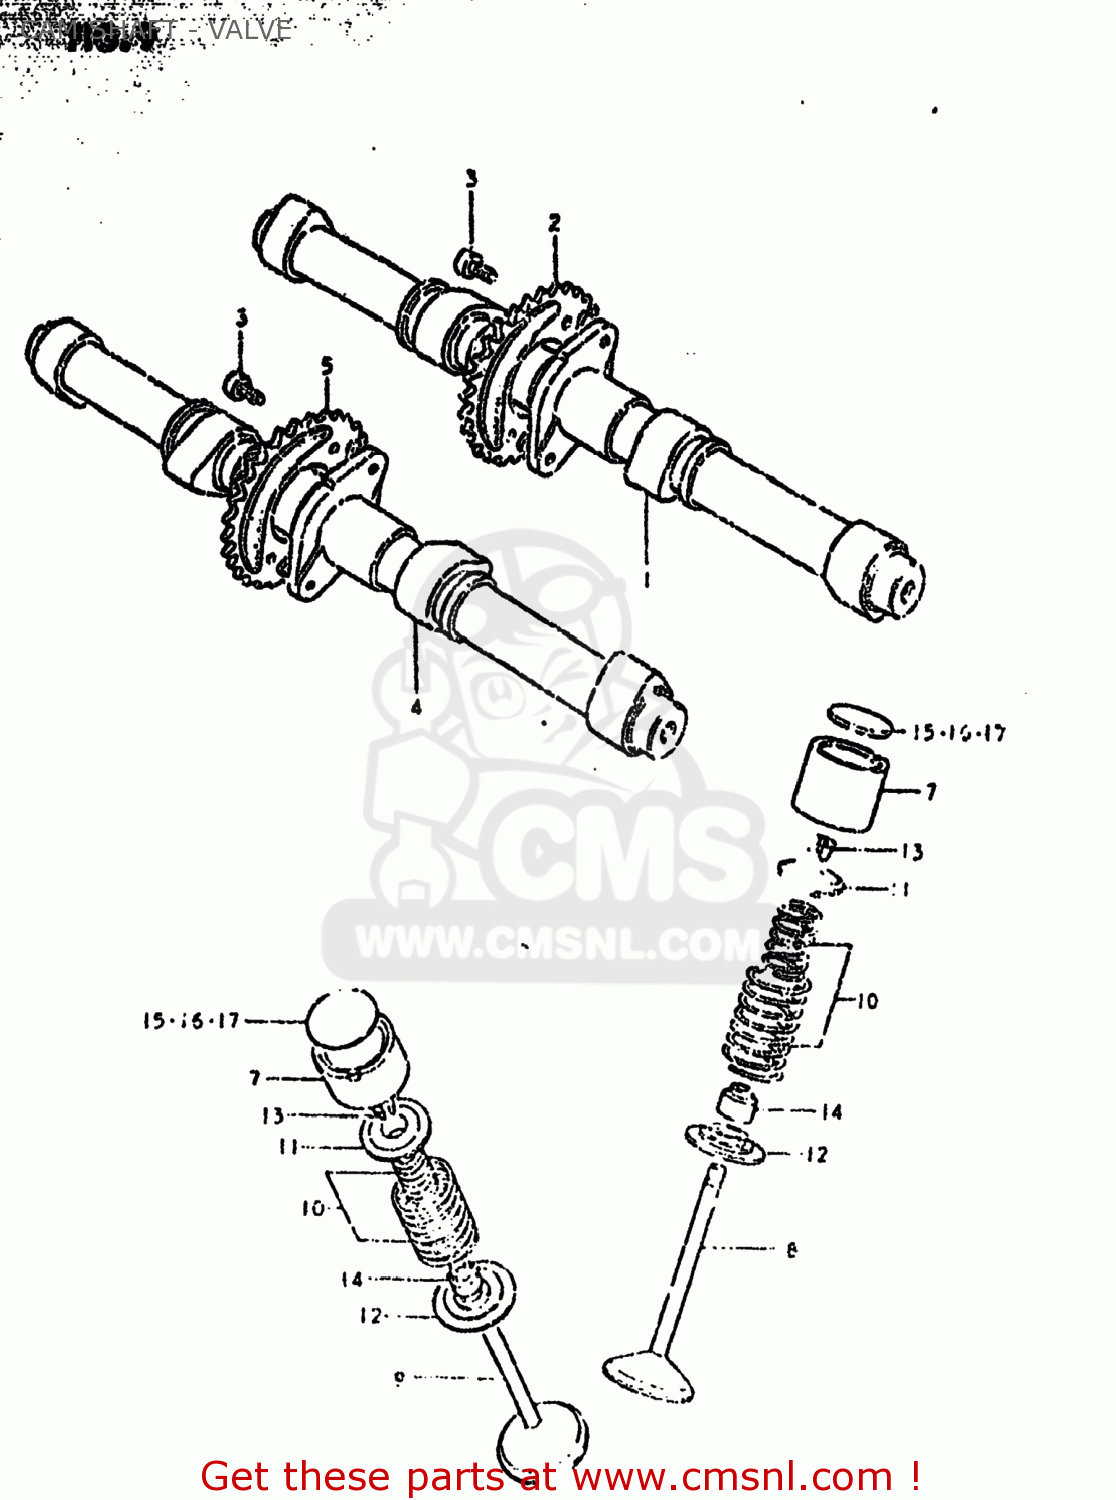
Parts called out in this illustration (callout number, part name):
1	CAMSHAFT
2	SPROCKET,CAMSHAFT
3	BOLT 6X11
4	CAMSHAFT,EXHAUST
5	SPROCKET,EXHAUST CAMSHAFT
6	BOLT 6X11
7	TAPPET
8	VALVE,INTAKE
9	VALVE,EXHAUST
10	SPRING SET,VALVE
11	RETAINER,VALVE SPRING
12	SEAT,VALVE SPRING
13	COTTER VALVE
14	SEAL,OIL(7X14.4X9)
15	SHIM,TAPPET
16	SHIM,TAPPET
17	SHIM,TAPPET
18	SHIM SET,TAPPET
19	CASE
